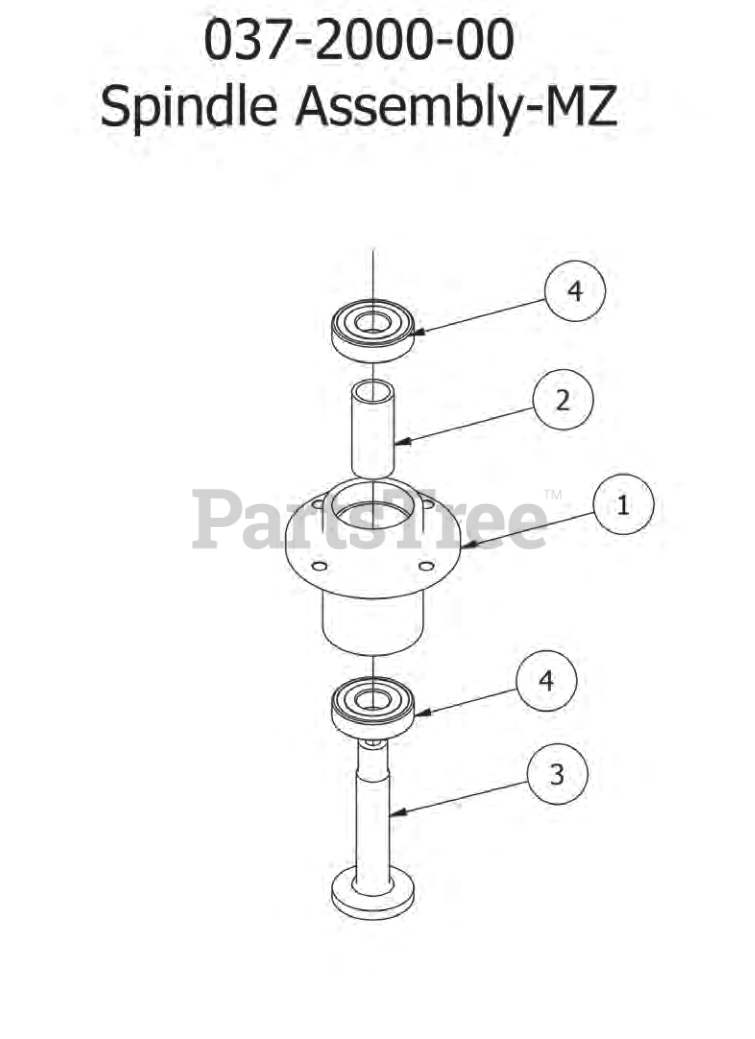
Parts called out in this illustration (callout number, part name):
1	MZ Spindle Housing
2	MZ Spindle Spacer-Component
3	MZ Spindle Shaft
4	MZ Spindle Bearing
